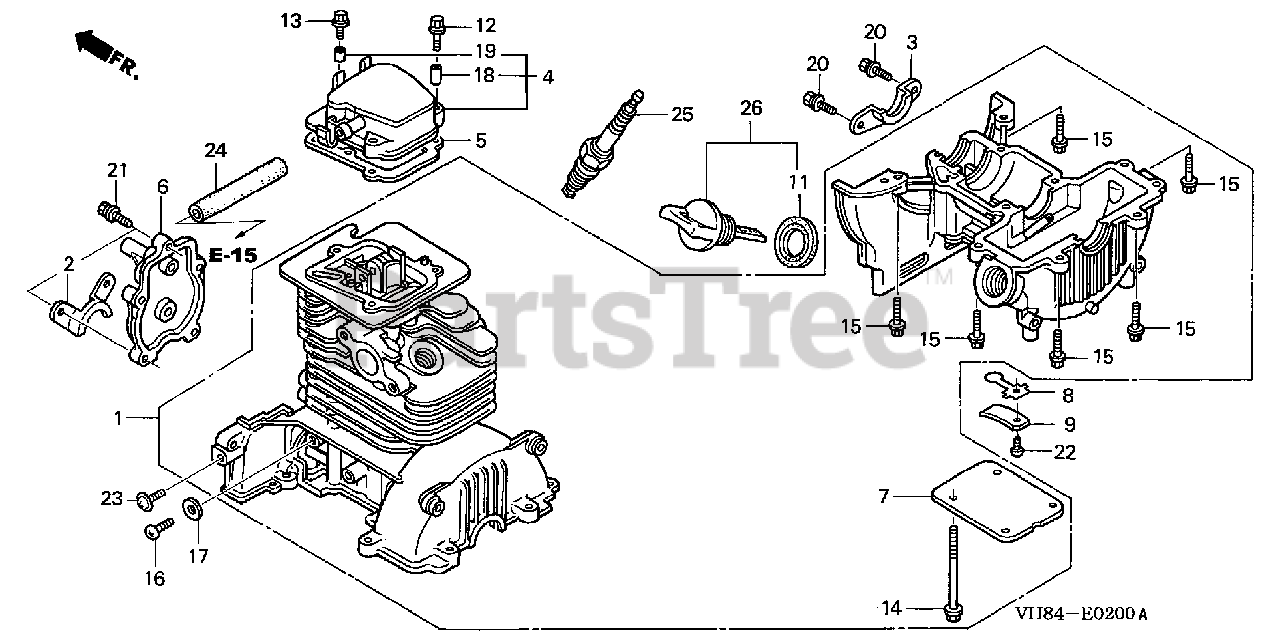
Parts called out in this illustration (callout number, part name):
1	CRANKCASE SET
2	GUARD A, GRASS
3	GUARD B, GRASS
4	COVER, HEAD
5	GASKET, HEAD COVER
6	COVER, CAMSHAFT
7	COVER, OIL OUTLET VALVE
8	VALVE, OIL OUTLET
9	PLATE, STOPPER
11	GASKET, OIL FILLER CAP
12	BOLT, FLANGE (5X22)
13	BOLT, FLANGE (5X14)
14	BOLT, FLANGE (5X55)
15	BOLT, FLANGE (5X18)
16	SCREW, PAN (6X8)
17	WASHER, SEALING (6.5MM)
18	COLLAR, HEAD COVER
19	COLLAR A, HEAD COVER
20	BOLT-WASHER (4X10)
21	BOLT-WASHER (4X16)
22	SCREW, PAN (3X5)
23	SCREW-WASHER (5X12)
24	BULK HOSE, VACUUM (7X3000) (7X68)
25	SPARK PLUG (U16FSR-UB)
25	SPARK PLUG (CR5HSB)
26	CAP ASSY., OIL FILLER
